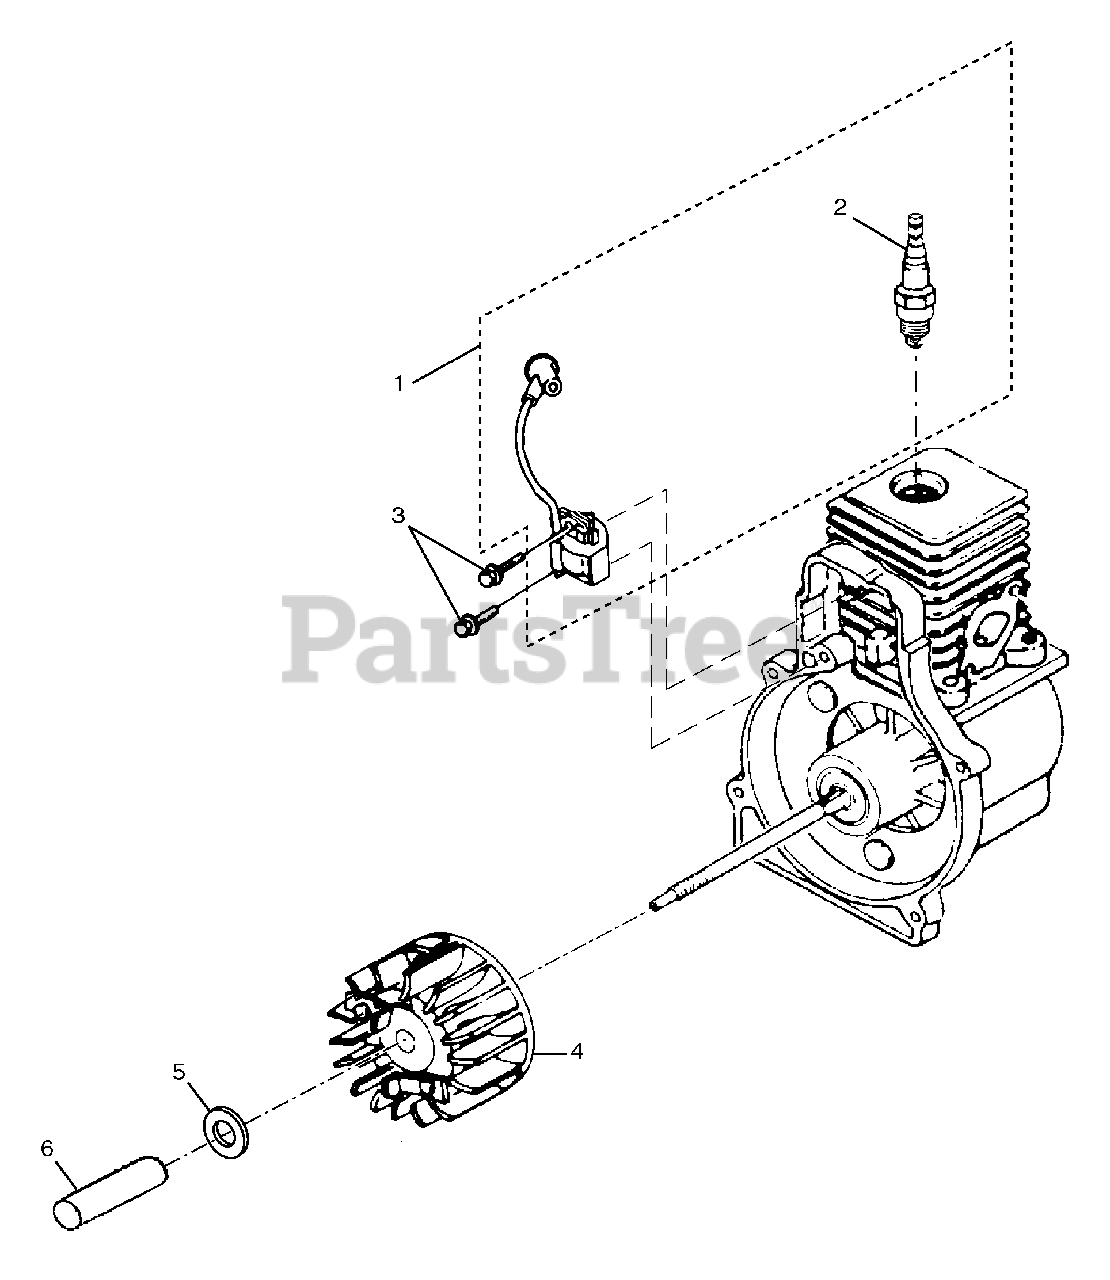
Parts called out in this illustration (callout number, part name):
1	IGNITION KIT WITH MODULE
2	SPARK PLUG
3	SCREW (8-32 x 1 in. TORX PAN HD)
4	ROTOR AND STARTER PAWLS
5	FLAT WASHER
6	FAN SPACER
